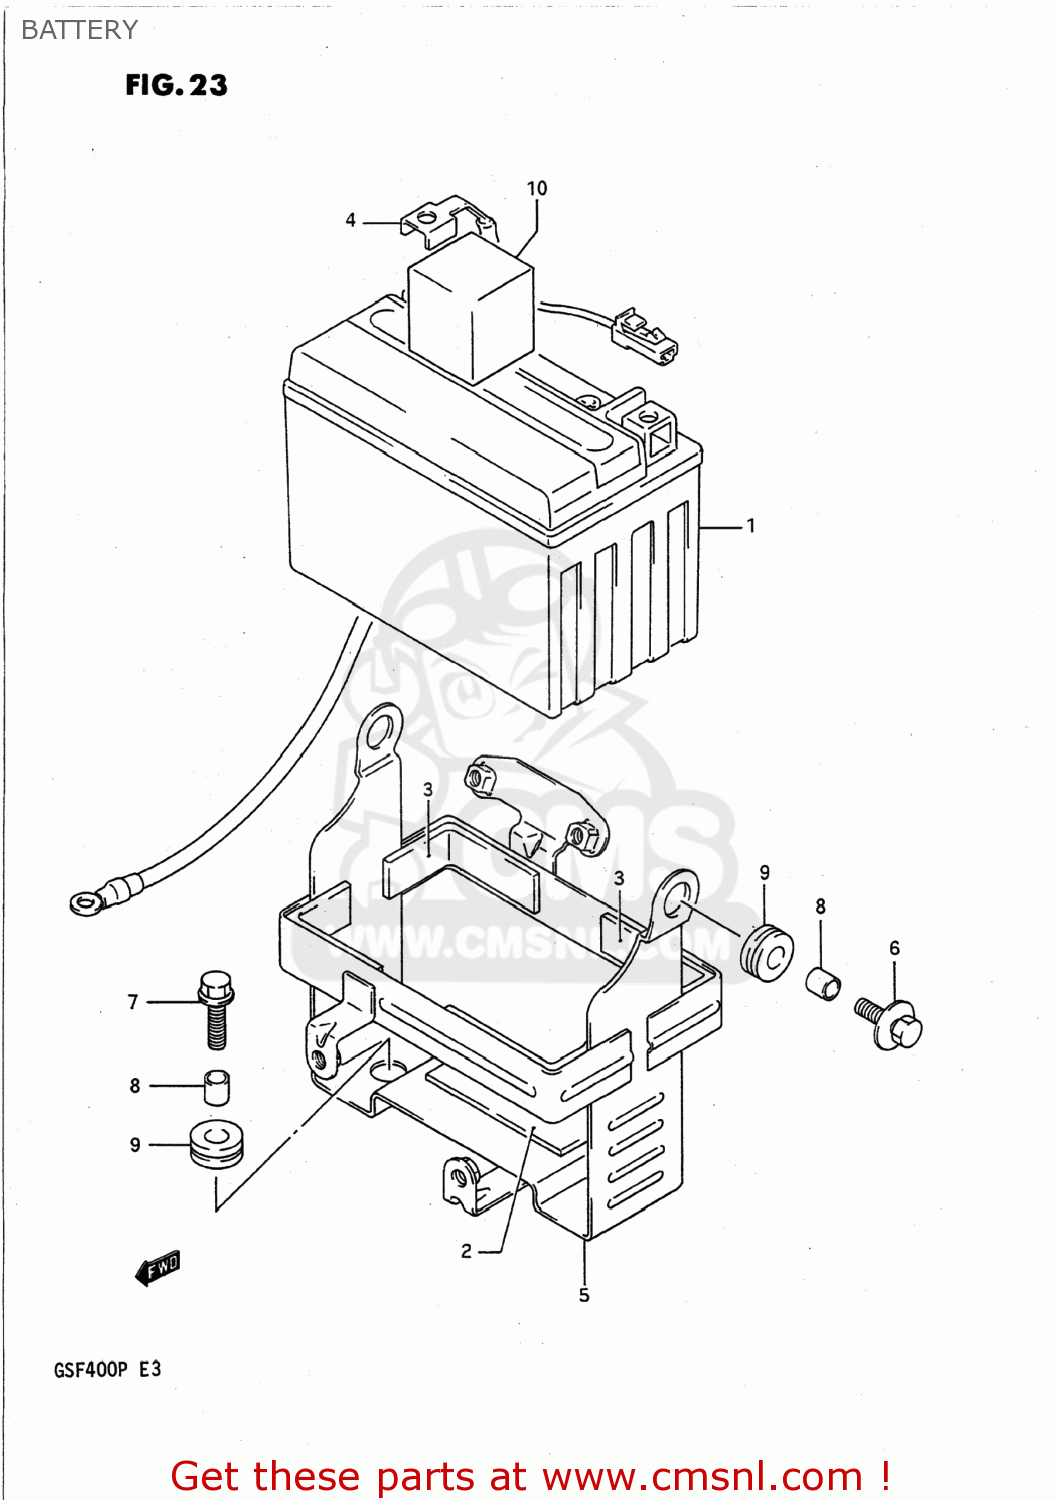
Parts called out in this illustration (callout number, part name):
1	BATTERY ASSEMBLY (12V) YTX
2	CUSHION,BATTERY(80X27X3)
3	PROTECTOR,20X9
4	WIRE,BATTERY MINUS LEAD
5	HOLDER,BATTERY
6	BOLT
7	BOLT 6X20
8	SPACER(6.2X9X7.5)
9	CUSHION
10	CUSHION,BATTERY 35X35X
